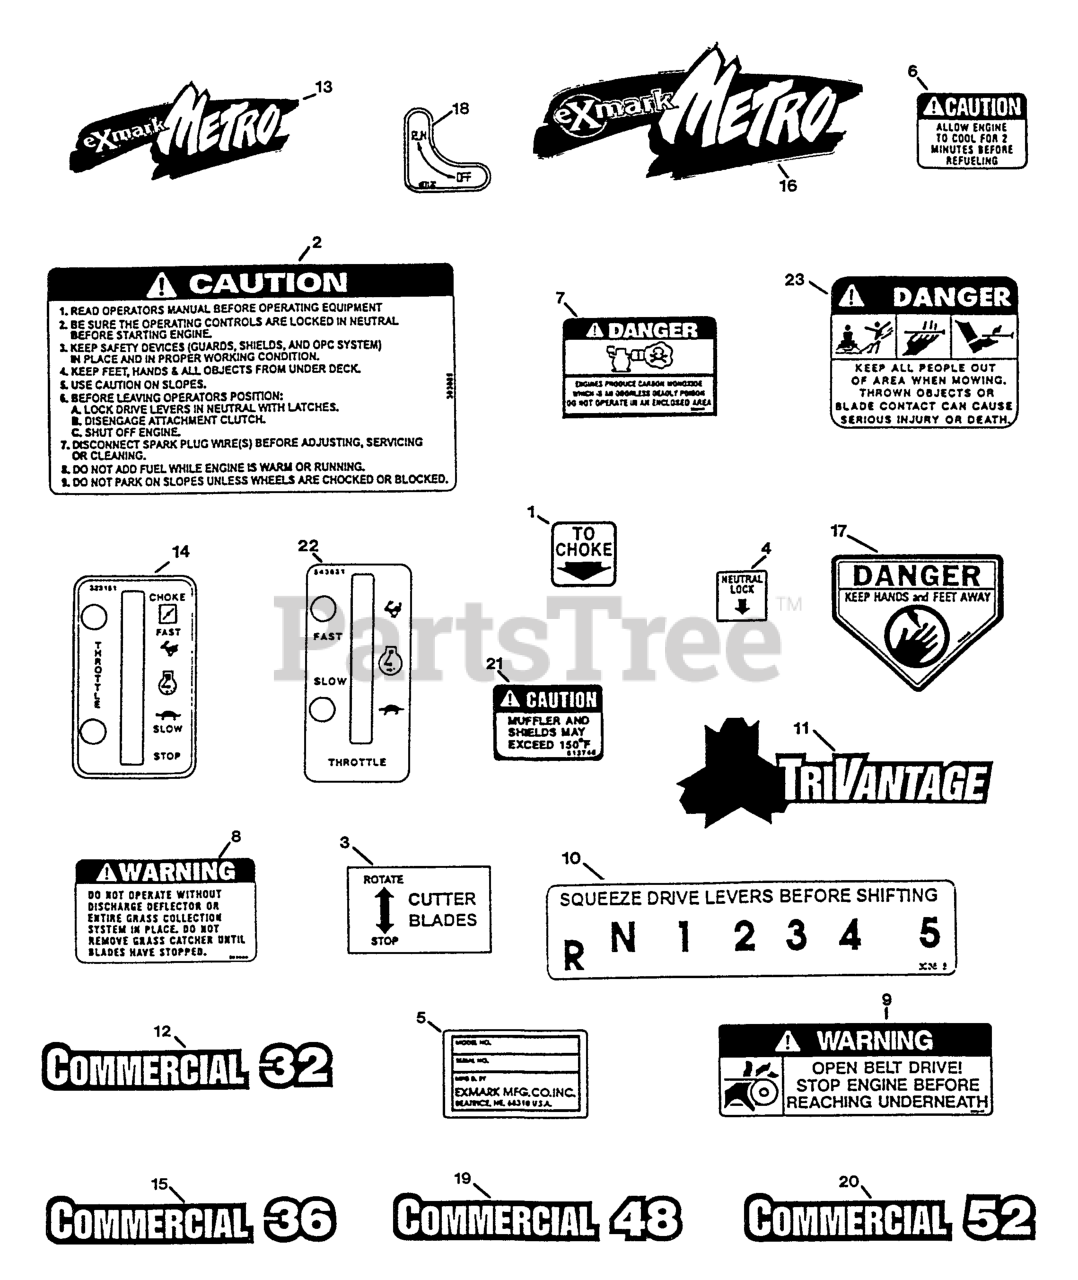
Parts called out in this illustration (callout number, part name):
2	LABEL,INSTRUCTION
3	DECAL,CUTTER BLADE
4	DECAL,NEUTRAL LOCK
8	DECAL-WARNING, DISCHARGE
9	DECAL,BELT DRIVE
10	DECAL,SHIFTER
12	DECAL,COMMERCIAL 32
15	DECAL,COMMERCIAL 36
17	DECAL-DANGER
19	DECAL,COMMERCIAL 48
20	DECAL,COMMERCIAL 52
23	DECAL-DANGER
